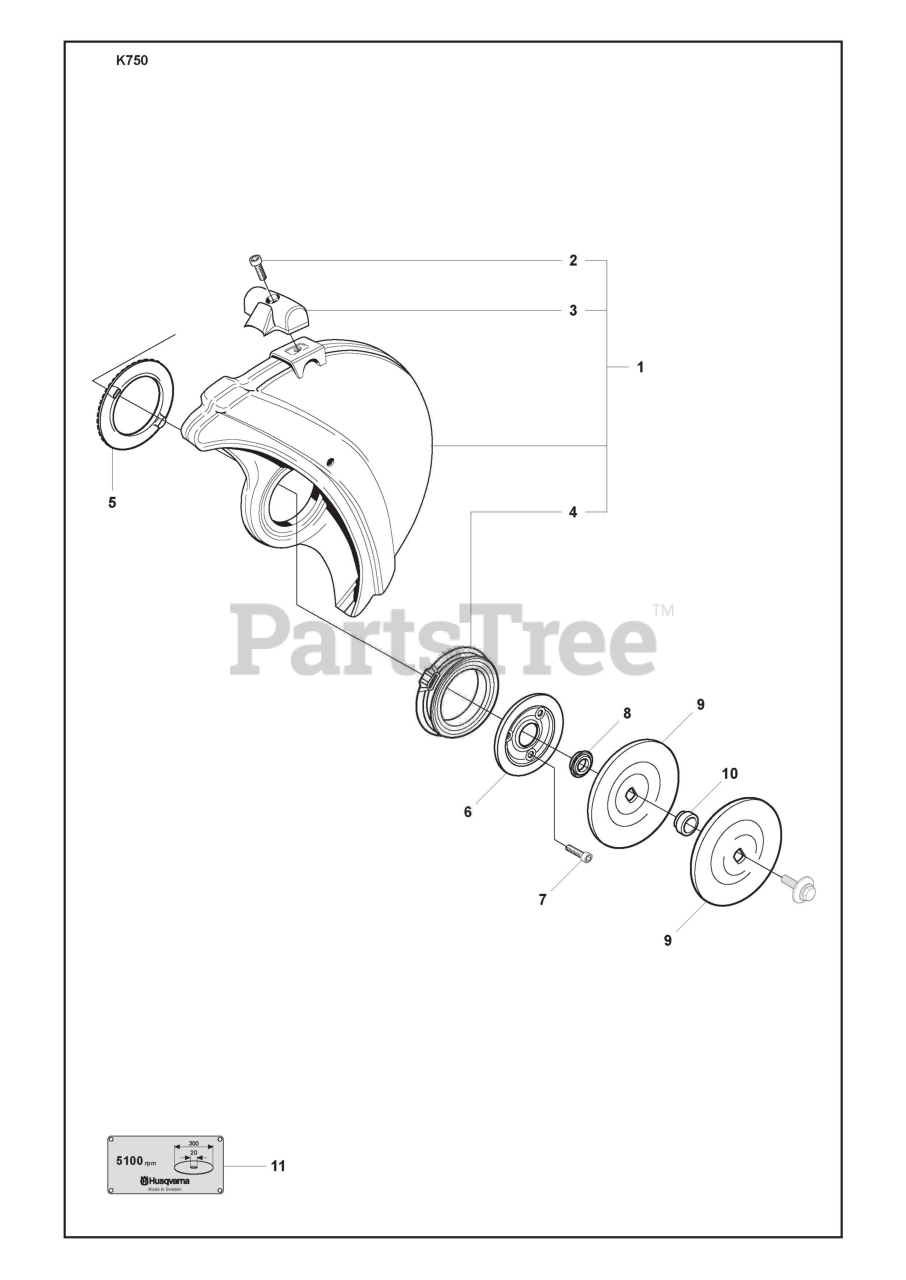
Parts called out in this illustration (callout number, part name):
1	WHEEL GUARD ASSY
2	SCREW
5	SCREEN PATTERN FLANG
8	SUPPORT FLANGE
9	FLANGE WASHER
10	BUSHING
11	LABEL
